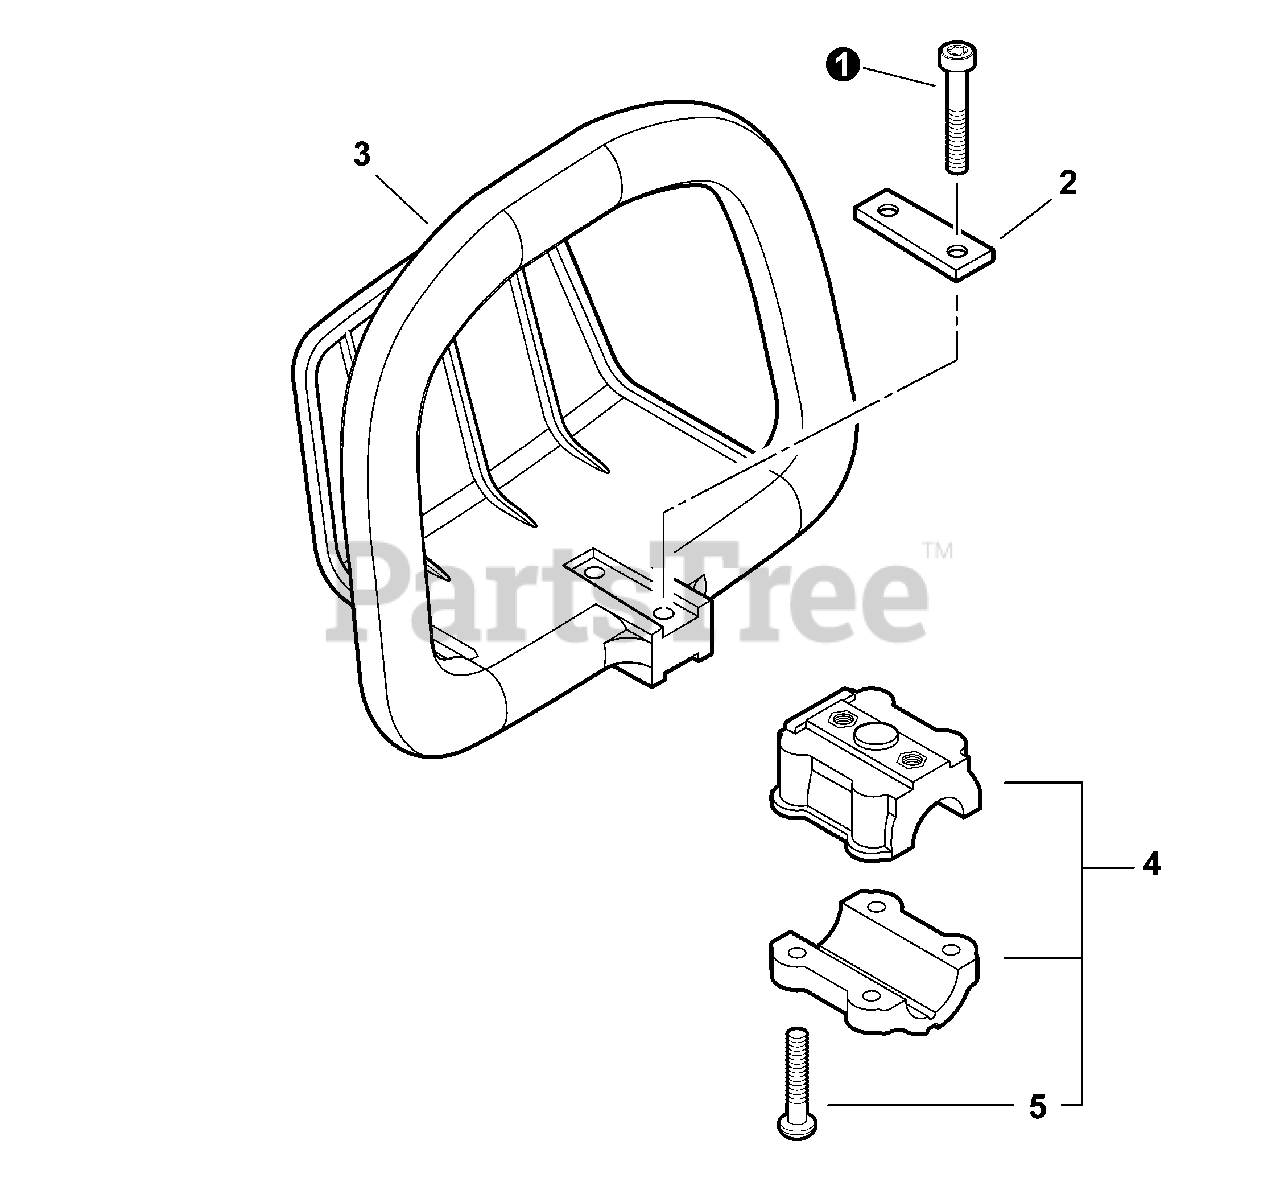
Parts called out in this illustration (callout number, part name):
1	SCREW - 5×30
2	PLATE, EYE
3	HANDLE - FRONT
4	BRACKET KIT
5	SCREW - 5×25
